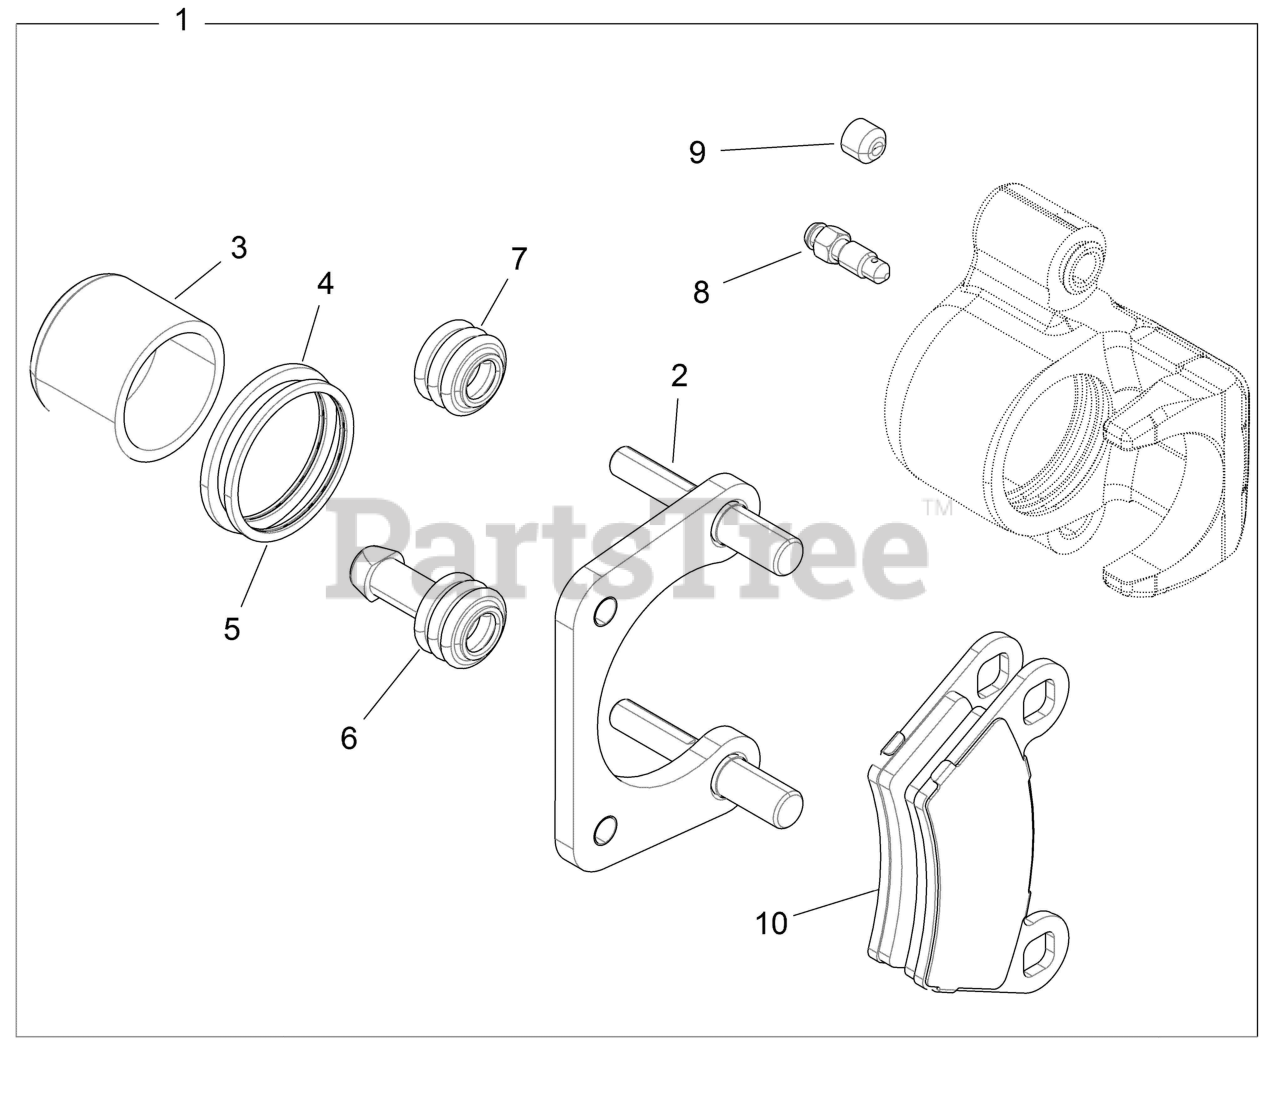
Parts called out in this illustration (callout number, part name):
1	ASM-CALIPER,BRAKE,1.5,LH,R MET
1	ASM-CALIPER,BRAKE,1.5,RH,R MET
2	ASM-CALIPER MOUNT,REAR,METRIC
3	PISTON-BRAKE,1.500
4	SEAL-CALIPER INNER,1.50"
5	SEAL-CALIPER,OUTER,1.50"
6	BOOT-PIN BUSHING
7	BOOT-PIN SEAL
8	SCR-M7X1.0,BLEEDER,OLIVE D
9	SCR-M10X1.0X8,SOC SET-OD
10	KIT-BRAKE PAD,ASM,1.5(INCL 4 P
